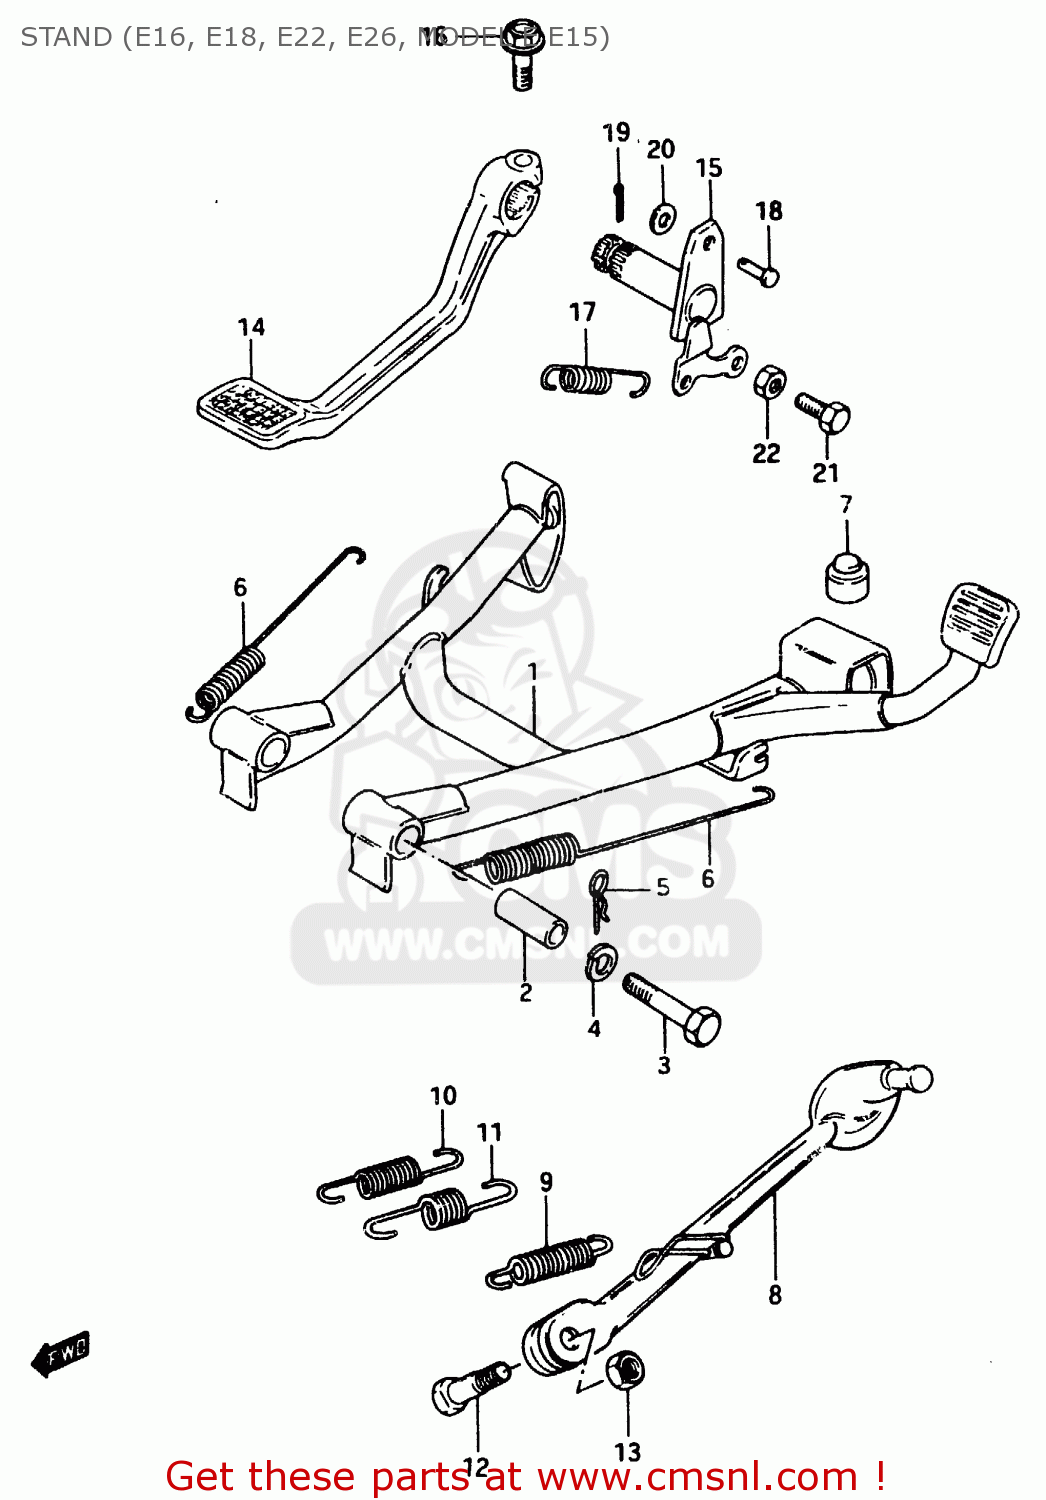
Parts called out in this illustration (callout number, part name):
1	STAND,CENTER
2	SPACER(10X16X38.8)
3	BOLT
4	LOCK WASHER
5	CLIP
6	SPRING
7	CUSHION
8	STAND, PROP
9	SPRING
10	SPRING
11	SPRING
12	BOLT(10X32)
13	NUTM10X1.25X8
14	PEDAL,BRAKE
15	ARM,BRAKE PEDAL
16	BOLT
17	SPRING
18	PIN
19	PIN
20	WASHER
21	BOLT
22	NUT
